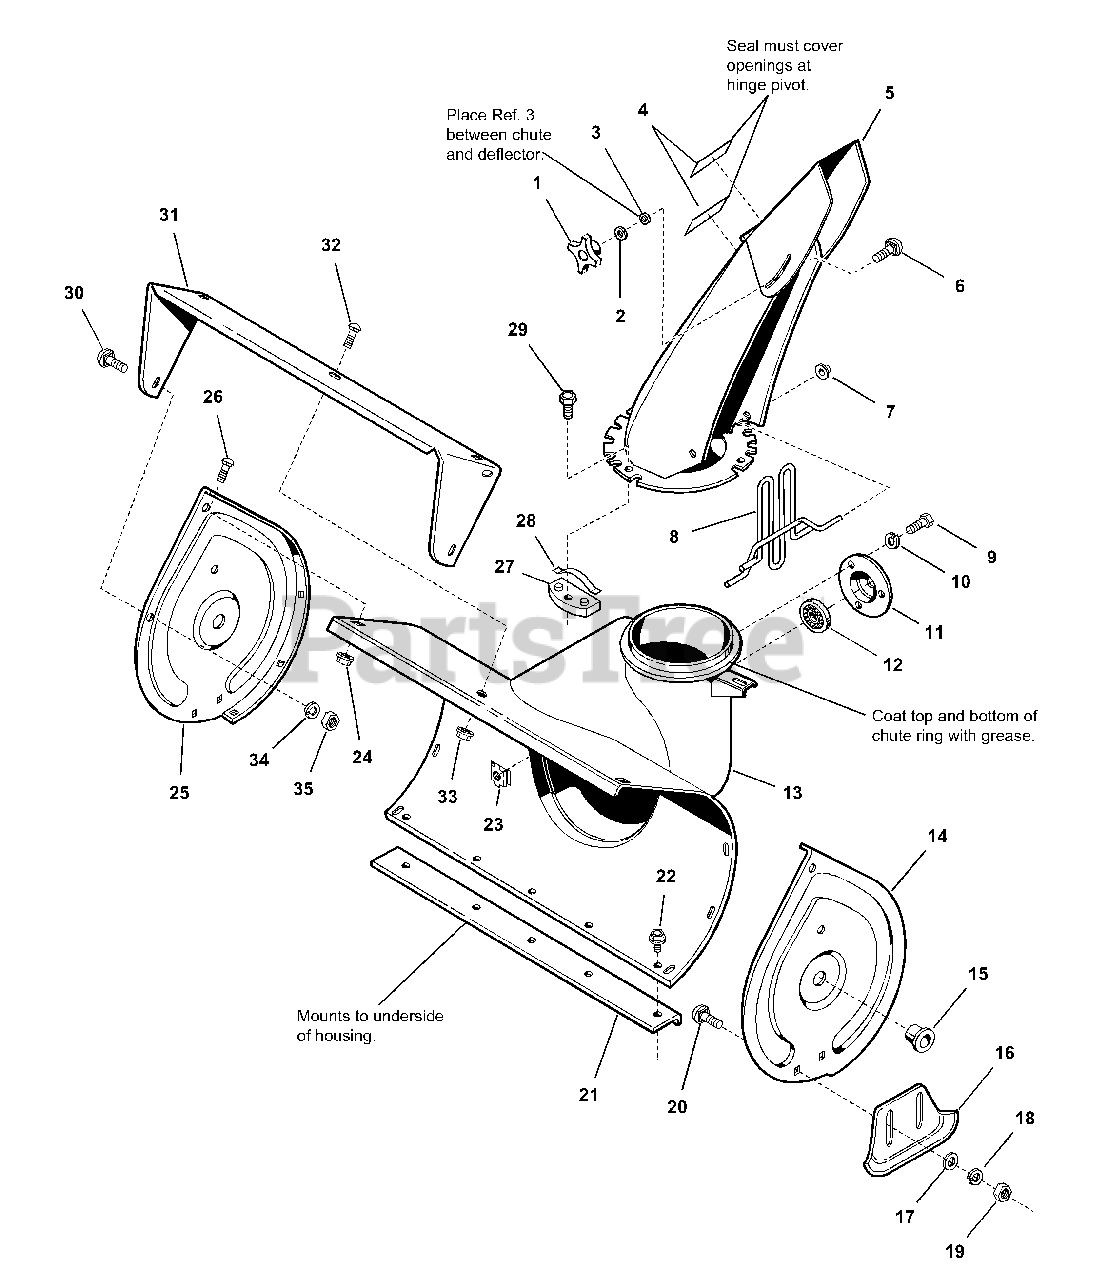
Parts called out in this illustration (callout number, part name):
2	WASHER, Flat, 5/16
3	WASHER, Nylon
4	DECAL, Hinge
5	CHUTE & DEFLECTOR ASSY.
6	BOLT, Carriage, 5/16-18 x 3/4
7	NUT, Push Pas, 1/4
8	CHUTE, Guard
9	CAPSCREW, Hex Hd. 5/16-18 x 5/8
10	LOCKWASHER, 5/16
11	RETAINER, Bearing
12	BEARING, Ball
13	HOUSING ASSY.
14	AUGER PLATE, L.H. End
16	SKID, Snowthrower
17	WASHER, Flat,13/32 x 7/8 x 5/64
18	LOCKWASHER, 3/8
19	NUT, Hex Hd. 3/8-16
20	BOLT, Carriage, 3/8-16 x 3/4
21	BLADE, Scraper
22	SCREW, Taptite, 1/4-20 x 3/8
23	NUT, Retainer, 5/16-18
24	NUT, Hex Flange, Whiz-Lock, 1/4-20
25	AUGER PLATE, R.H. End
26	BOLT, Carriage, 1/4-20 x 1/2
27	HOLD DOWN, Chute
28	SPRING, Flat
29	SCREW, Hex Washer Hd., Plastite #10-14 x 5/8
30	CAPSCREW, Hex Hd., 1/4-20 X 5/8
31	WRAPPER, Extension
32	BOLT, Rd. Hd. 1/4-20 X 1/2
33	NUT, Hex Fl. 1/4-20
34	LOCKWASHER, Spring
35	NUT, Hex, 1/4-20
